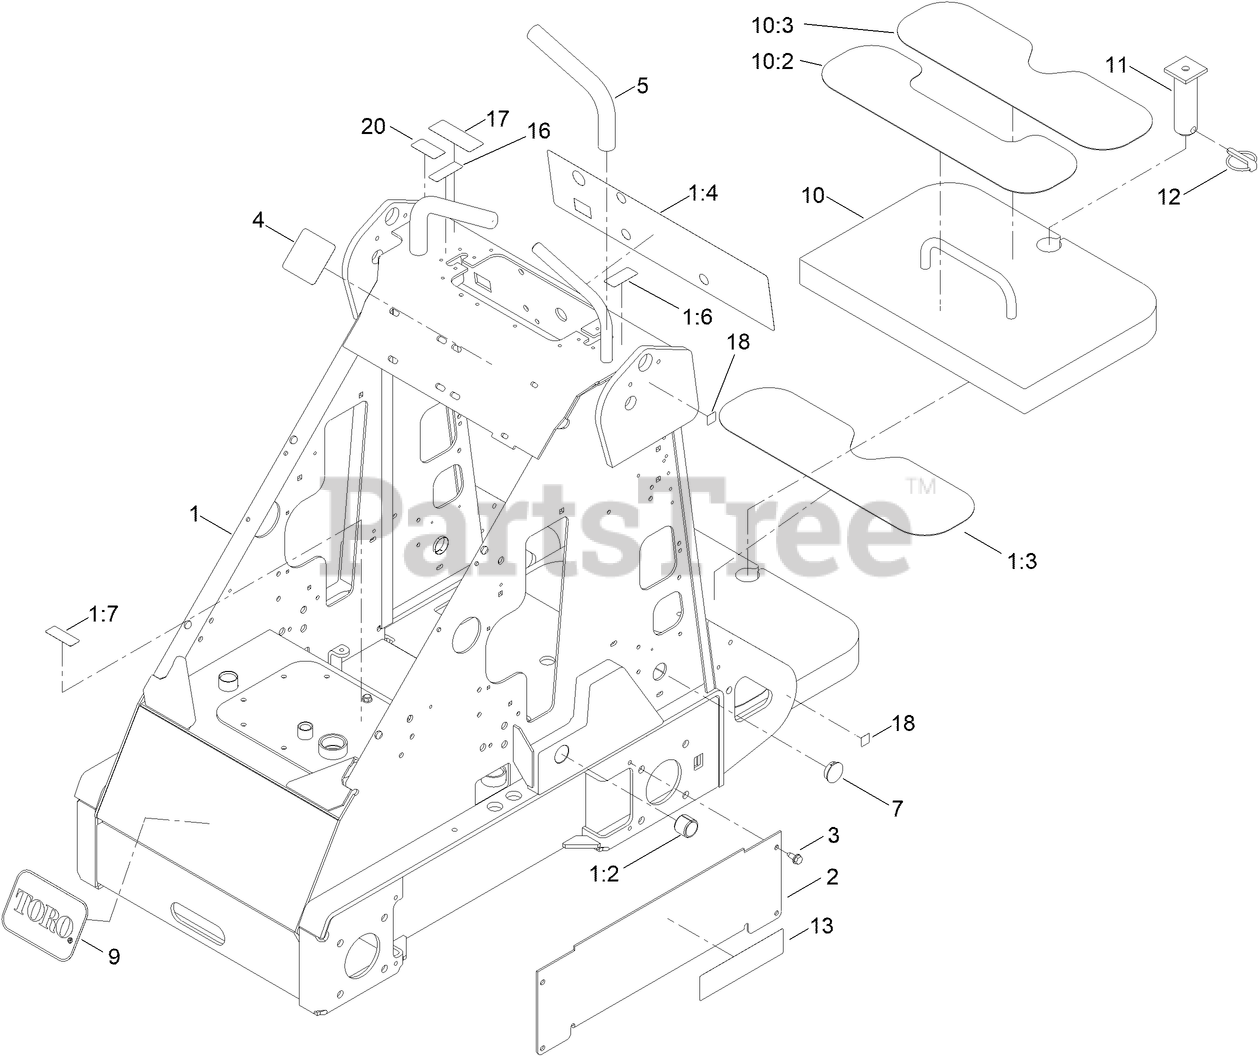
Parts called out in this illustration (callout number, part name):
1	FRAME ASM
1:2	BUSHING-TENSION
1:3	TREAD-FOOT
1:4	DECAL-CONTROL PANEL
1:6	DECAL-THROTTLE
1:7	DECAL-OIL, HYD
2	COVER-HOSE
3	SCREW-HWHTF
4	DECAL-SELECTOR, SPEED
5	GRIP-CUSHION
7	PLUG-HOLE
9	DECAL
10	COUNTERWEIGHT ASM
10:2	TREAD-FOOT
12	PIN-LYNCH
16	DECAL-CHOKE
17	DECAL-ARRESTOR, SPARK
18	DECAL-POINT, LIFT
20	DECAL-PROTECTION, EAR
